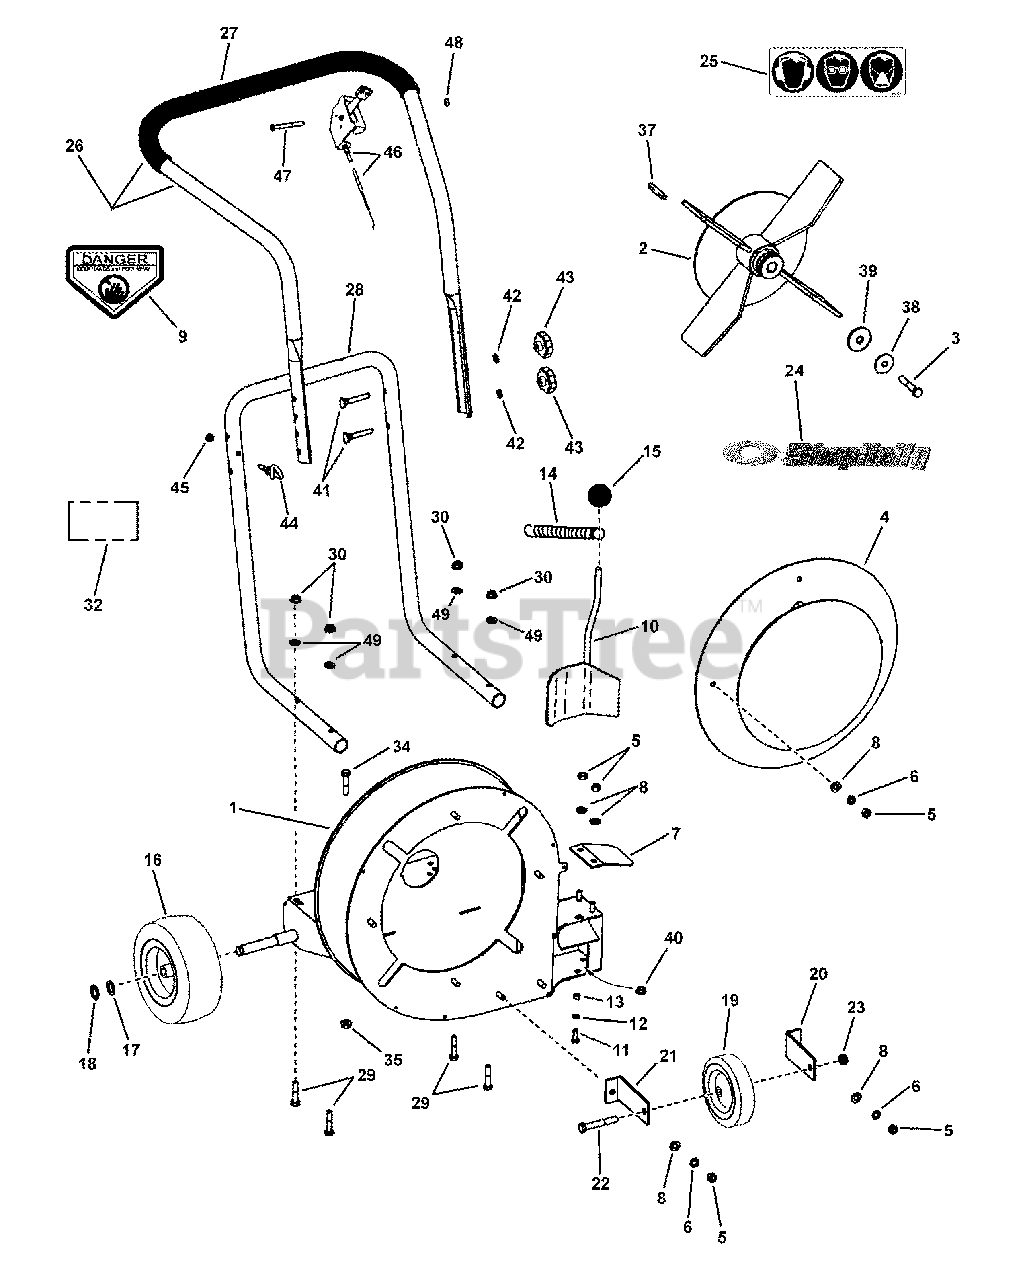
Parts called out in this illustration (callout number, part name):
1	BASE & HOUSING ASSEMBLY, 52 Classic
2	IMPELLER ASSEMBLY, Steel 4 Blade 15.00 O.D.
3	CAPSCREW, 3/8-24 x 2 Hex Head, GR5
4	INTAKE BAFFLE ASSEMBLY
5	NUT, 5/16-18 Hex, GR5 or B
6	WASHER, 5/16 Split Lock
7	DEFLECTOR, Side Air
8	WASHER, .34 x .69 x .08 Flat
9	DECAL, Danger, Cut Finger
10	DOOR FRONT/SIDE DISCHARGE ASSEMBLY
11	CAPSCREW, 1/4-20 x 3/4 Hex Head, GR5
12	WASHER, .263 x .375 x .062 Split Lock
13	BUSHING, Steel Sleeve .250 ID x .375 OD x .25 Long
14	SPRING, Extension (was 3024502)
15	KNOB, #230 Dimco
16	WHEEL & TIRE ASSEMBLY, Sawtooth 4.10/3.50-4 Kenda
17	WASHER, .64 x .99 x .05 Flat
18	RING, External Retaining (TRU1500-62)
19	WHEEL, 6.00 x 1.50 Semi-Pneumatic
20	BRACKET, Caster - RH
21	BRACKET, Caster - LH
22	CAPSCREW, 3/8-16 x 2-1/2 Hex Head, GR5
23	NUT, 3/8-16 Hex Center Lock, GR5 or B
24	DECAL, Simplicity Logo
25	DECAL, Personal Protection
26	ASSEMBLY, Upper Handle & Grip - Narrow (p/n 3033876 + grip)
27	GRIP, 1.0 x 21-1/2 Foam
28	HANDLE, Lower Folding- Narrow- Blower
29	CAPSCREW, 5/16-18 x 1-3/4 Hex Head, GR5
30	NUT, 5/16-18 Hex Nyloc
32	DECAL, 5.5 HP Briggs & Stratton
34	CAPSCREW, 5/16-18 x 1-1/2 Hex Head, GR5 (Engine Mounting Hardware)
35	NUT, 5/16-18 Hex Flange Lock, GR5 (Engine Mounting Hardware)
37	KEY, 1/4 Square x 2
38	WASHER, .411/.406 I.D. Cone
39	WASHER, .468 x 1.625 x .25 Flat
40	BUSHING, Flanged .375 x .500 x .25 (.625 x .063 Flange)
41	CARRIAGE BOLT, 5/16-18 x 2, GR2
42	WASHER, 5/16 Internal Tooth Lock
43	KNOB, Folding Handle
44	GUIDE, Rope
45	NUT, 1/4-20 Hex Center Lock, GR5 or B
46	THROTTLE CONTROL, Briggs & Stratton
47	CAPSCREW, 1/4-20 x 2 Hex Head, GR5
48	NUT, 1/4-20 Hex Nyloc
49	WASHER, 5/16 Curved
